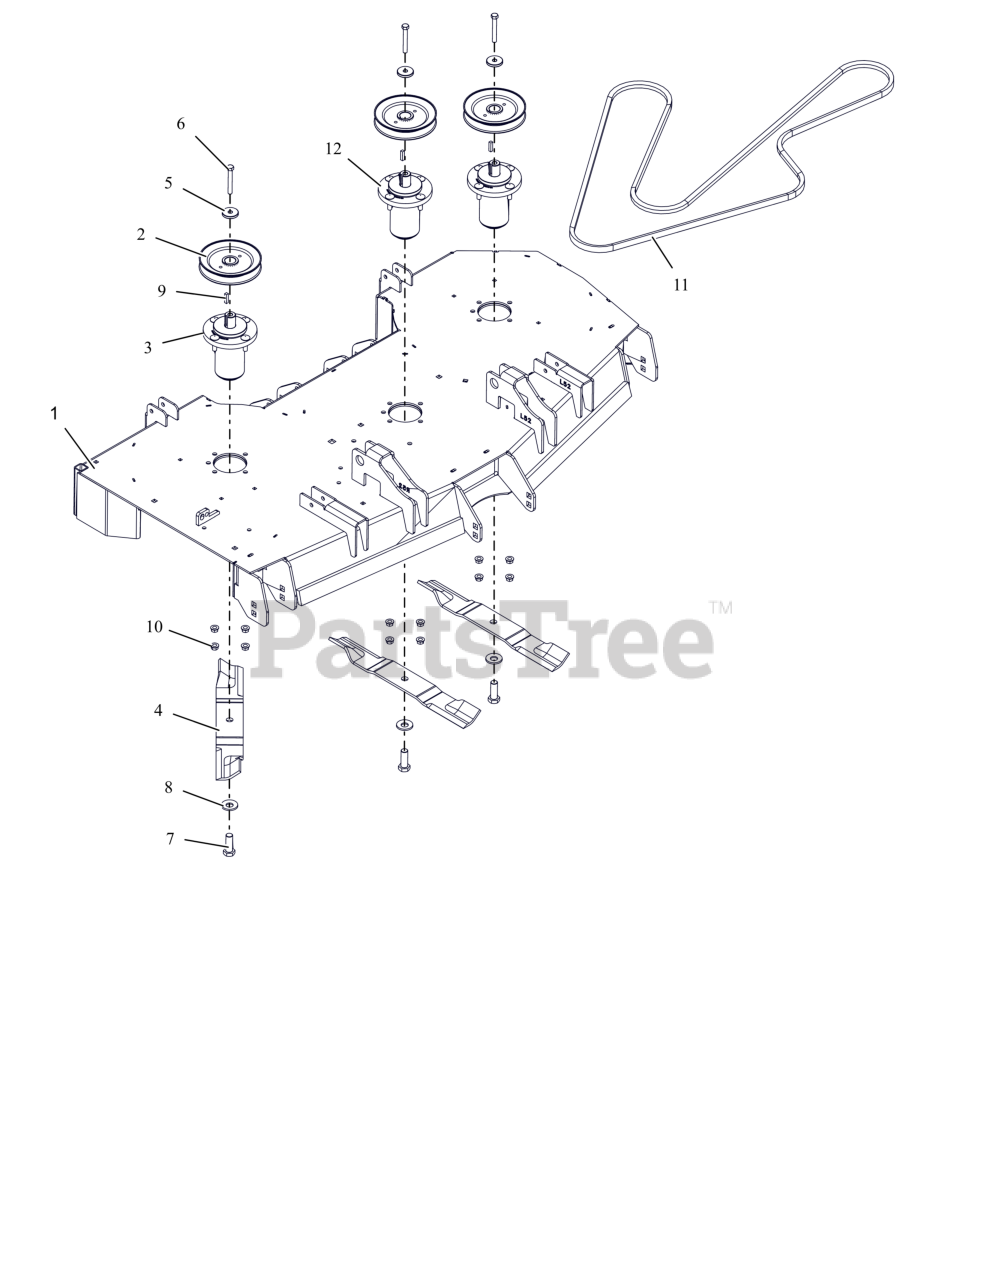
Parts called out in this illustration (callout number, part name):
1	KIT- SERVICE 52" DECK W/DECALS
2	PULLEY, V - 1.000 ID X 5.750 OD
3	ASM, ALUM SPINDLE
4	BLADE, 18.00" MOWER (HI-LIFT)
5	RETAINER, SHEAVE
6	BLT, HEX .38-16X2.75 G8 ZCC
7	BLT, HEX .62-18X1.75 G8 ZCC
8	WSHR-BLVL .669X1.535X.138
9	KEY, SQ .25X.25X1.00 RC 40-50
10	NUT-LK-CTR-FLG .375-16 GF ZCC
11	V-BELT, B RAW EDGE EPDM
12	ASM, MAINT FREE ALUM SPINDLE
